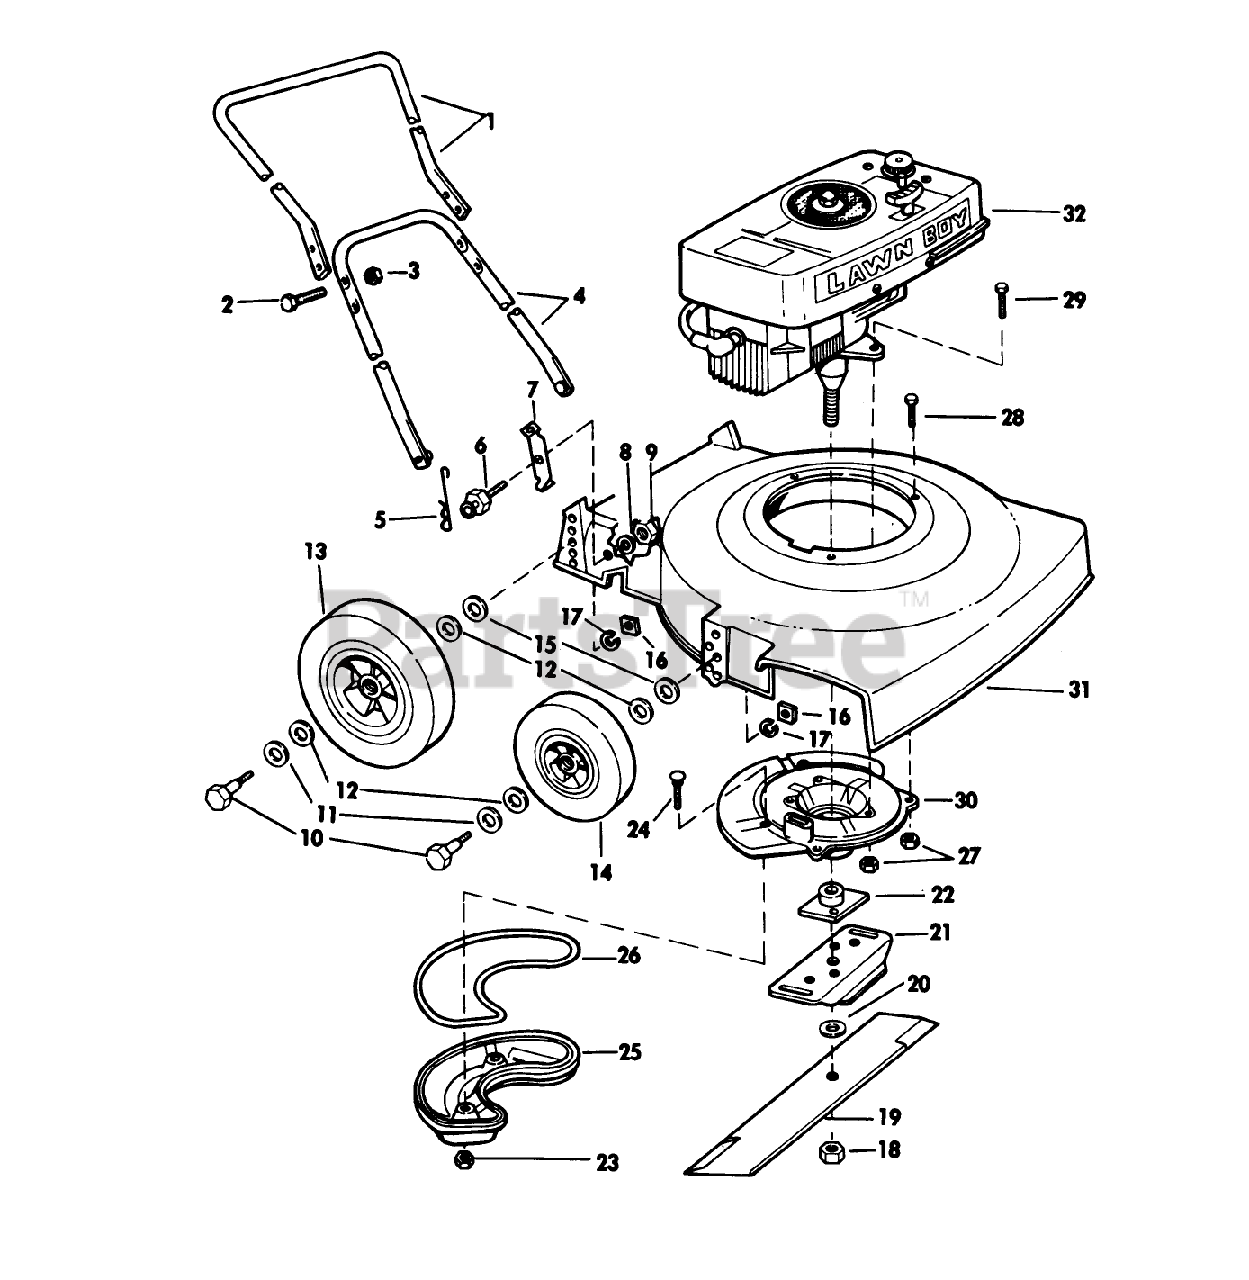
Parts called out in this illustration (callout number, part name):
8	Lockwasher
15	WASHER WROUGHT
17	WASHER, LOCK
18	NUT-BLADE
22	PLATE AND COLLAR ASM
23	LOCKNUT E
